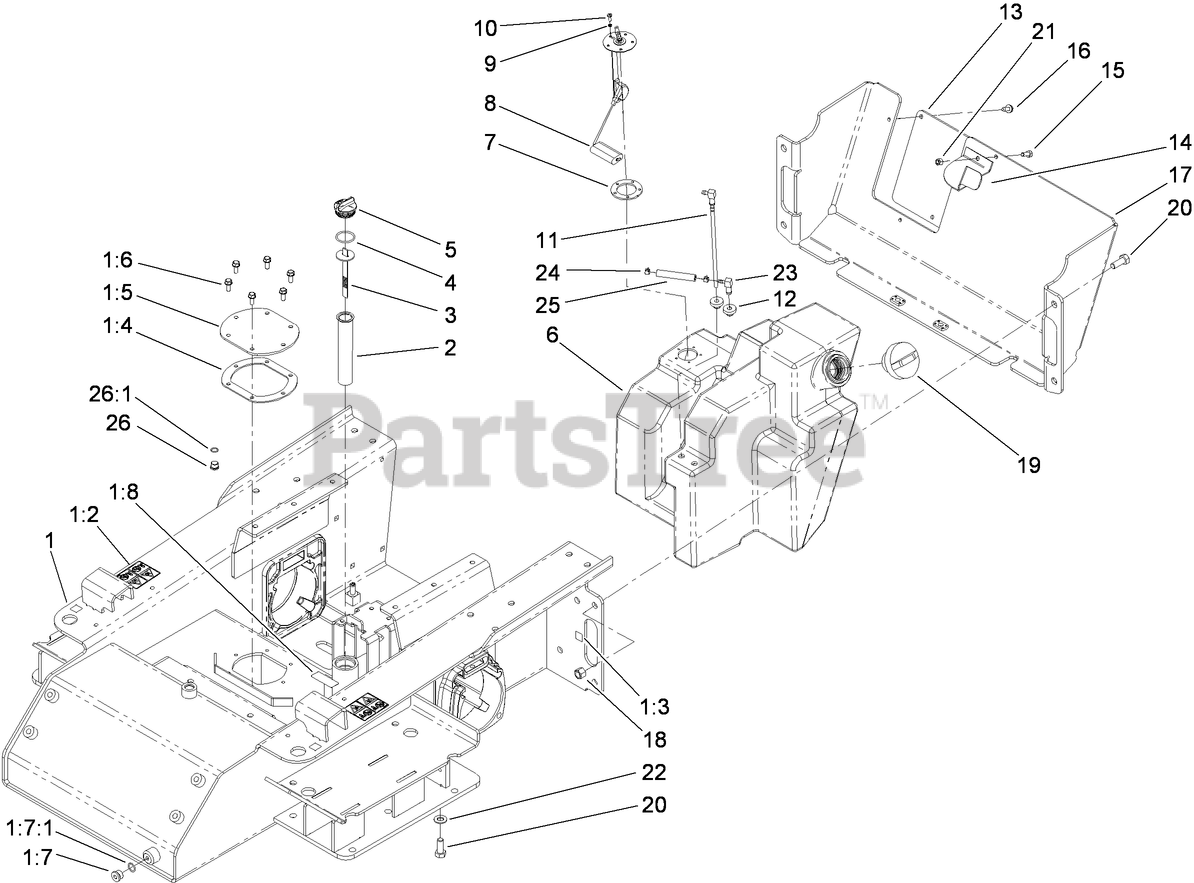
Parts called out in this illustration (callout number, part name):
1	CHASSIS ASM
1:2	DECAL-WARNING
1:3	DECAL-POINT, LIFT
1:4	GASKET-COVER, ACCESS
1:5	COVER-TANK
1:6	SCREW
1:7	PLUG-HEX
1:7:1	O-RING
1:8	DECAL-OIL, HYD
2	FILTER-SCREEN
3	DIPSTICK-OIL
4	O-RING
5	PLUG-PLASTIC
6	TANK-FUEL
7	GASKET-SENDER, FUEL
8	SENDER-FUEL
9	WASHER-LOCK
10	SCREW-PPH
11	PIPE-STAND
12	BUSHING
13	PANEL-REAR
14	CLAMP-TANK, FUEL
15	SCREW-HH
16	SCREW-HWHTF
17	COVER-REAR
18	NUT-LOCK, NI
19	CAP-DIESEL
20	SCREW-HH
21	NUT-LOCK, NI
22	WASHER-FLAT
23	FITTING-ELBOW, 90 DEG
24	CLAMP-HOSE
25	HOSE-FUEL
26	PLUG-HEX, HOLLOW
26:1	O-RING
